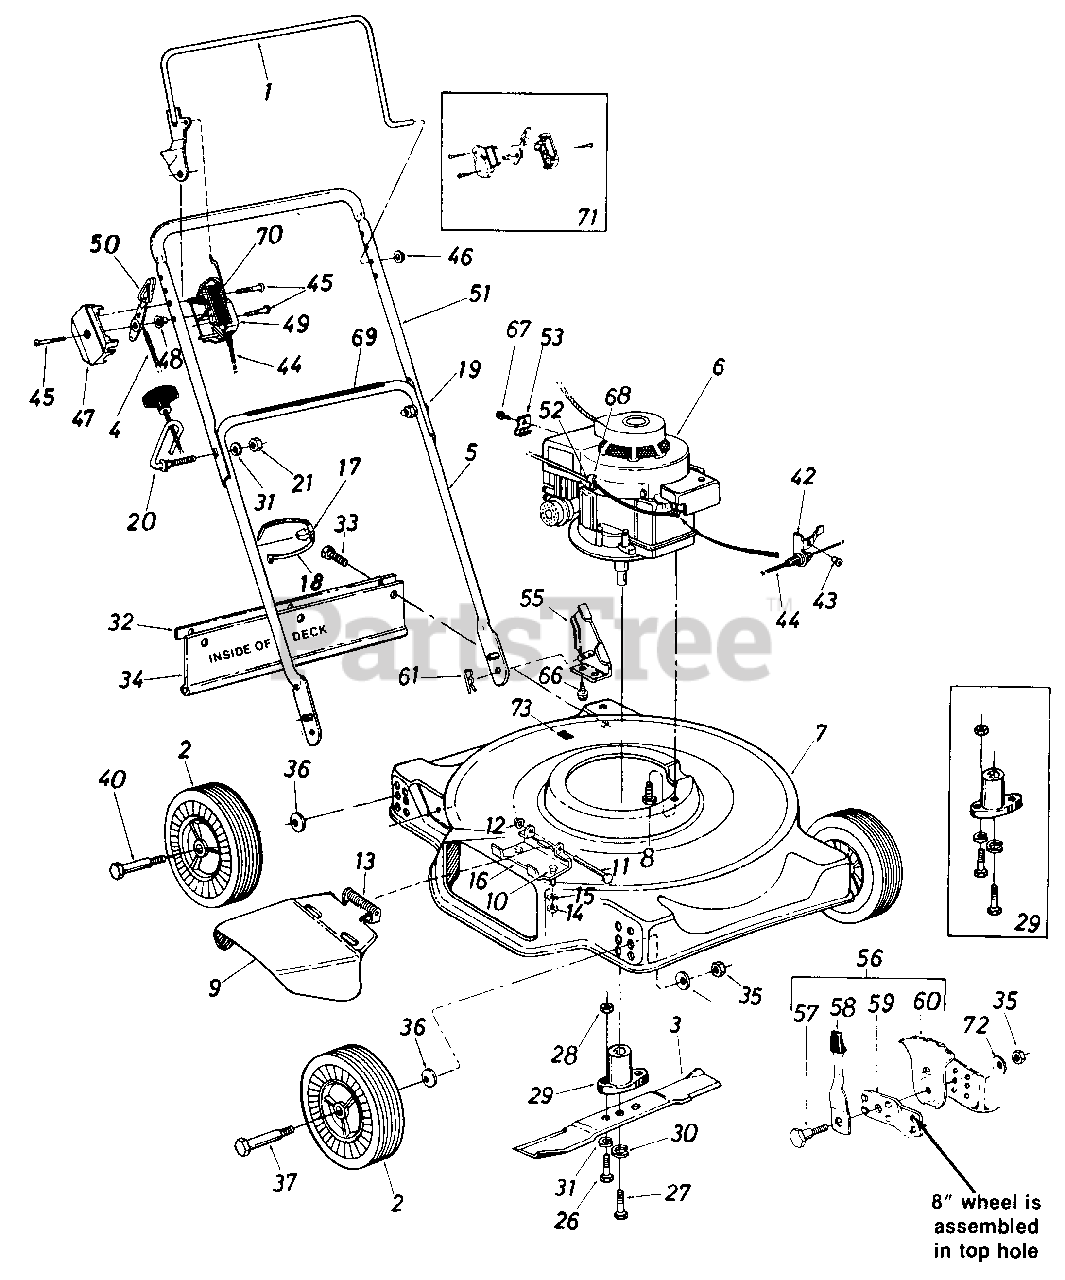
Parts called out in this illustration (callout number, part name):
1	Control Handle Ass'y. R.H.
2	Wheel Ass'y. Comp.
4	Throttle Control Wire 39"
5	Lower Handle
6	Engine
9	Chute Deflector Ass'y.
10	Hex Bolt 1/4-20 x .50" Lg*
11	Hinge Pin 1/4" Dia. x 3.88 Lg.
12	Push Cap .25" Rod
13	Torsion Spring
14	Hex Nut 1/4-20 Thd*
15	L-Wash. 1/4" I.D*
16	Deflector Hinge Plate
17	Plastic Cable Anchor
19	Curved Carriage Bolt 5/16-18 x 1.38" Lg.
20	Rope Guide Bolt
21	Hex Nut 5/16-18 Thd*
26	Hex Bolt 5/16-24 x 1.00" Lg. (Grade 5) Special
27	Hex Bolt 3/8-24 x 2.25" Lg. (Grade 5)
28	Hex Nut 5/16-24 Thd.
29	Blade Adapter Kit
30	L-Wash. 3/8" I.D. H.D.
31	L-Wash. 5/16" I.D.
32	Retainer Strip
33	Hex Wash. Hd. AB-Tap Scr. 1/4" x .62" Lg.
34	Rear Flap Ass'y.
35	Hex Nut 3/8-16 Thd*
36	Bell-Wash. .400" I.D. x .88"
37	Front Axle Bolt
40	Rear Axle Bolt
42	Cable Bracket
43	Pop Rivet .156" Dia. x .379
44	49" Control Cable Blue
45	Truss Mach. Scr. #12 x 1.50"
46	Cap Speed Nut 5/16" Rod
47	Control Panel Half
48	Control Disc Pin
49	Clutch Panel Half
50	Throttle Control Lever
51	Upper Handle
52	Hex "B" Tap Scr. #10 x .38"
53	Casing Clamp
55	Handle Mount Brkt. Ass'y. L.H.
56	Height Adjuster Ass'y. Comp. R.H.
57	Shoulder Bolt .500" Dia. x .357
58	Spring Lever Ass'y. w/ Knob
59	Pivot Bar
60	Index Plate
61	Hairpin Cotter
66	Hex Wash. Hd. Self-Tap Scr. 5/16-18 x .50" Lg.
67	Hex Wash. Hd. AB-Tap Scr. #8 x .38" Lg.
68	Cable Clip
69	Instruction Label Handle
70	Control Label Throttle
71	Kit Control Housing Comp
72	Belleville Wash. .39 I.D. x 1.4 O.D.
73	Plastic Plug
8072-000-6	Hardware Pack
